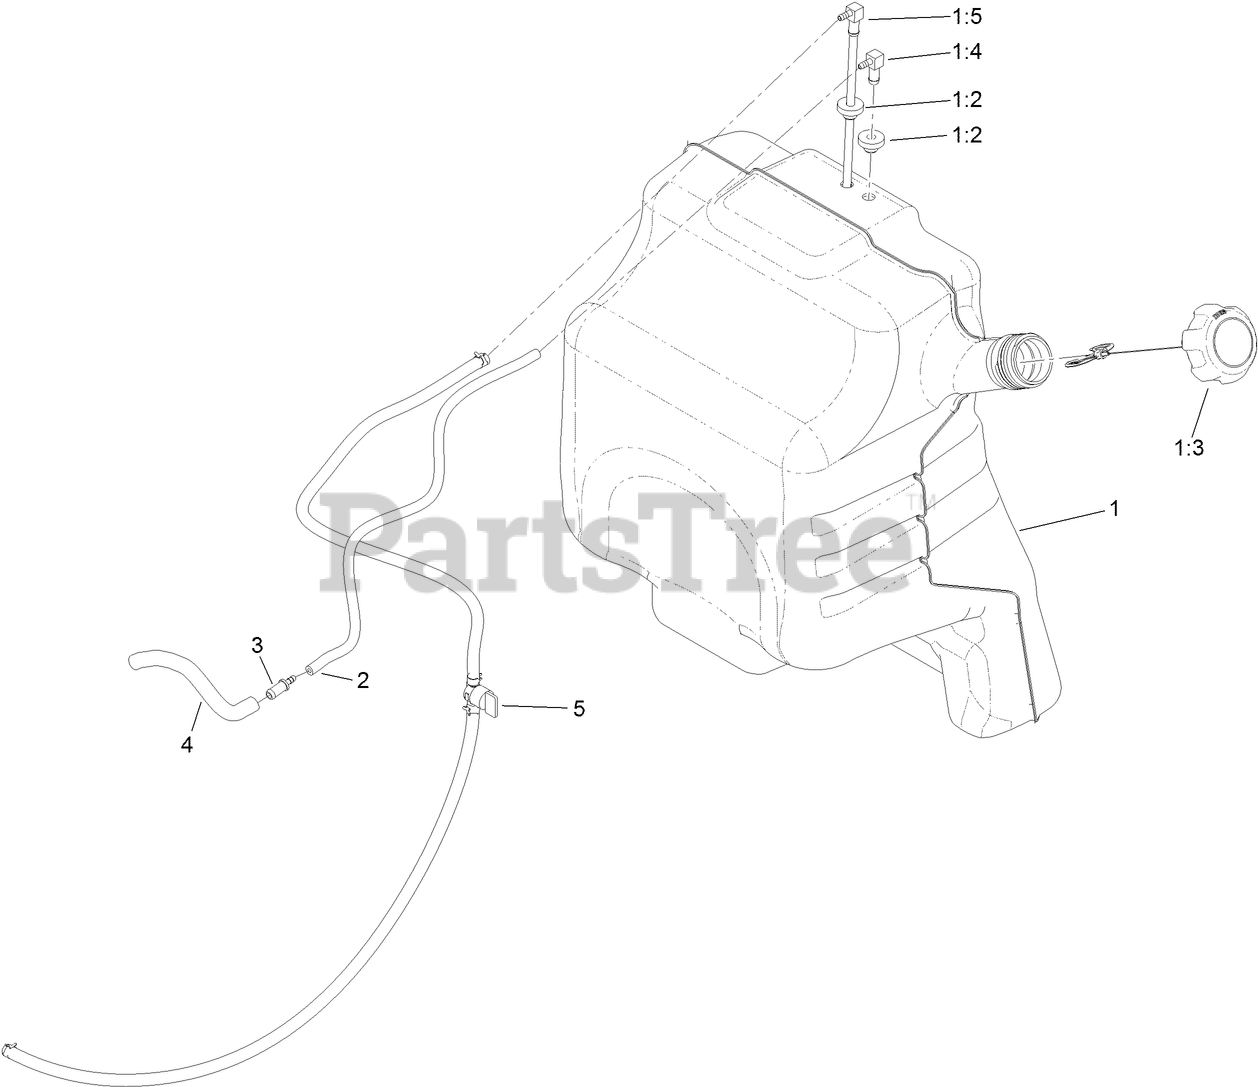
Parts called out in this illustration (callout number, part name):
1	FUEL TANK ASM
1:2	BUSHING
1:3	CAP-FUEL
1:4	FITTING-ELBOW, 90 DEG
1:5	FUEL TUBE ASM
2	HOSE-FUEL
3	FITTING-STRAIGHT
4	HOSE-FUEL
5	FUEL LINE ASM
